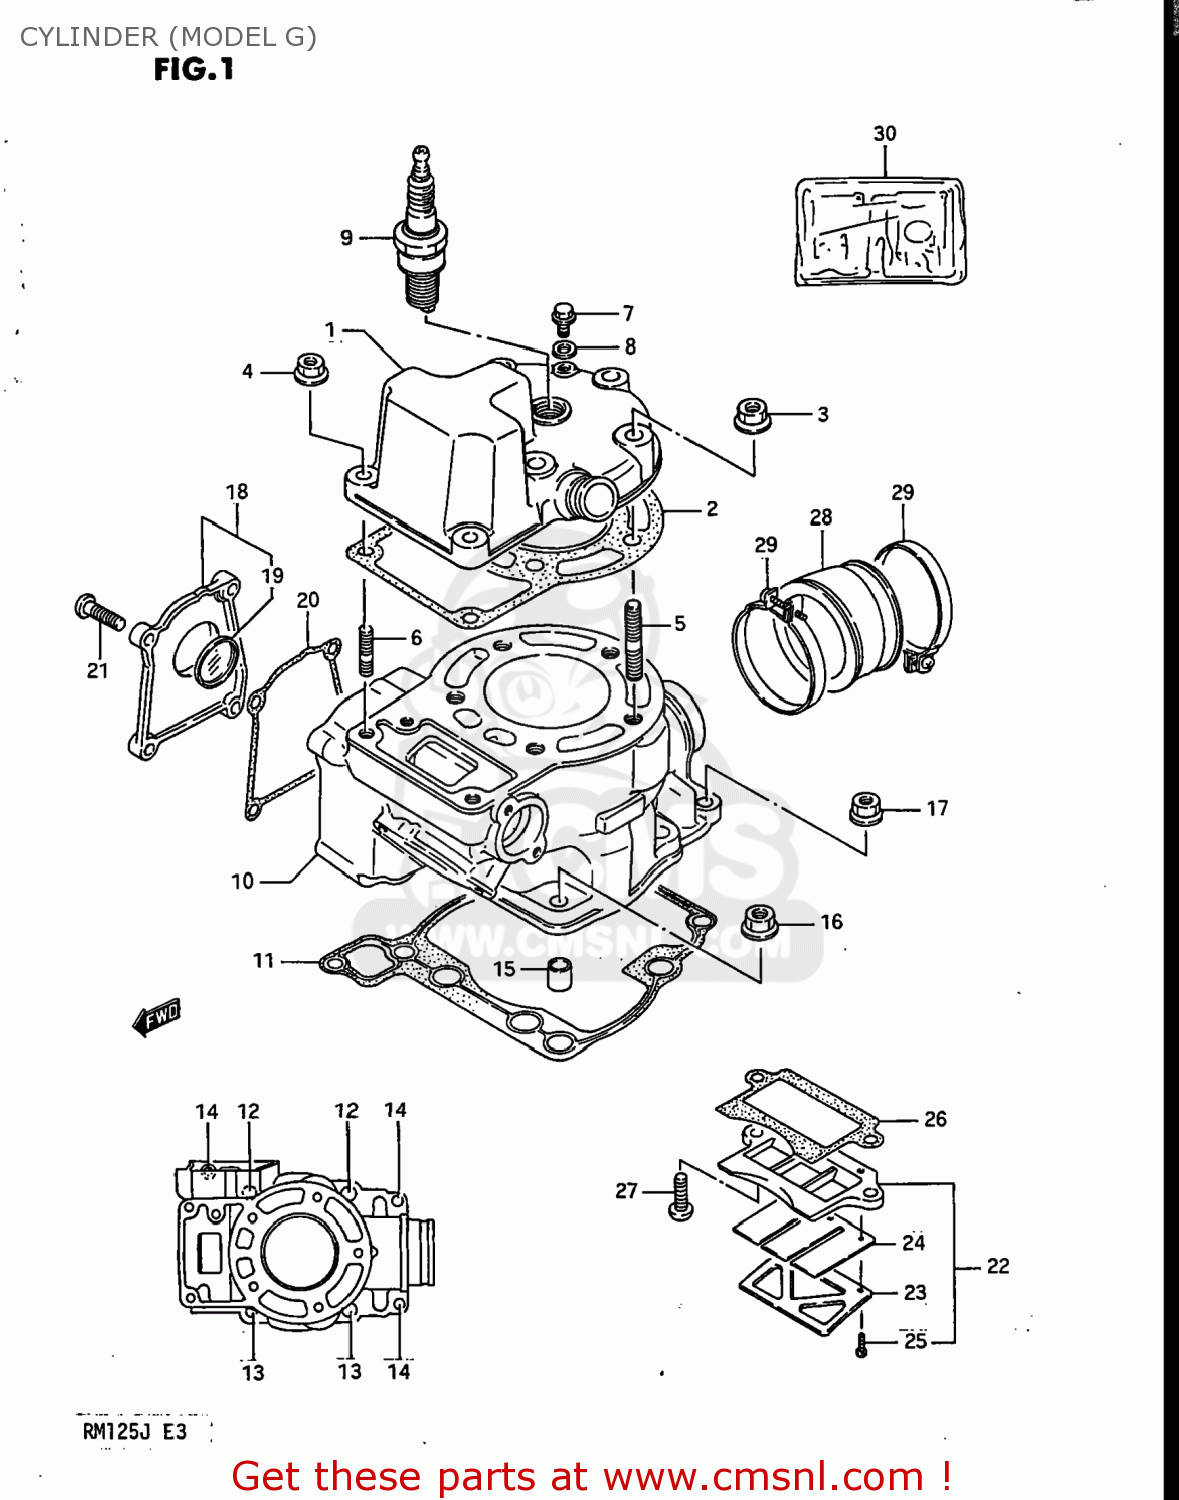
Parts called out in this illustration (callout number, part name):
1	HEAD,CYLINDER
2	GASKET,CYLINDER HEAD (MCA)
3	NUT
4	NUT
5	BOLT,STUD
6	BOLT,STUD
7	UNION
8	GASKET(6.2X11X1).2 (NAS)
9	SPARK PLUG
10	CYLINDER
11	GASKET,CYLINDER (MCA)
12	BOLT,STUD L:25
13	BOLT,STUD
14	BOLT,STUD
15	PIN
16	NUT
17	NUT
18	COVER COMP,CYLINDER
19	LENS,CYLINDER COVER
20	GASKET,CYLINDER COVER ( (MCA)
21	SCREW
22	VALVE ASSEMBLY,REED
23	STOPPER,REED VALVE
24	VALVE,REED
25	SCREW,REED VALVE
26	GASKET,REED VALVE (MCA)
27	SCREW
28	PIPE,INTAKE
29	CLAMP
30	GASKET SET (MCA)
